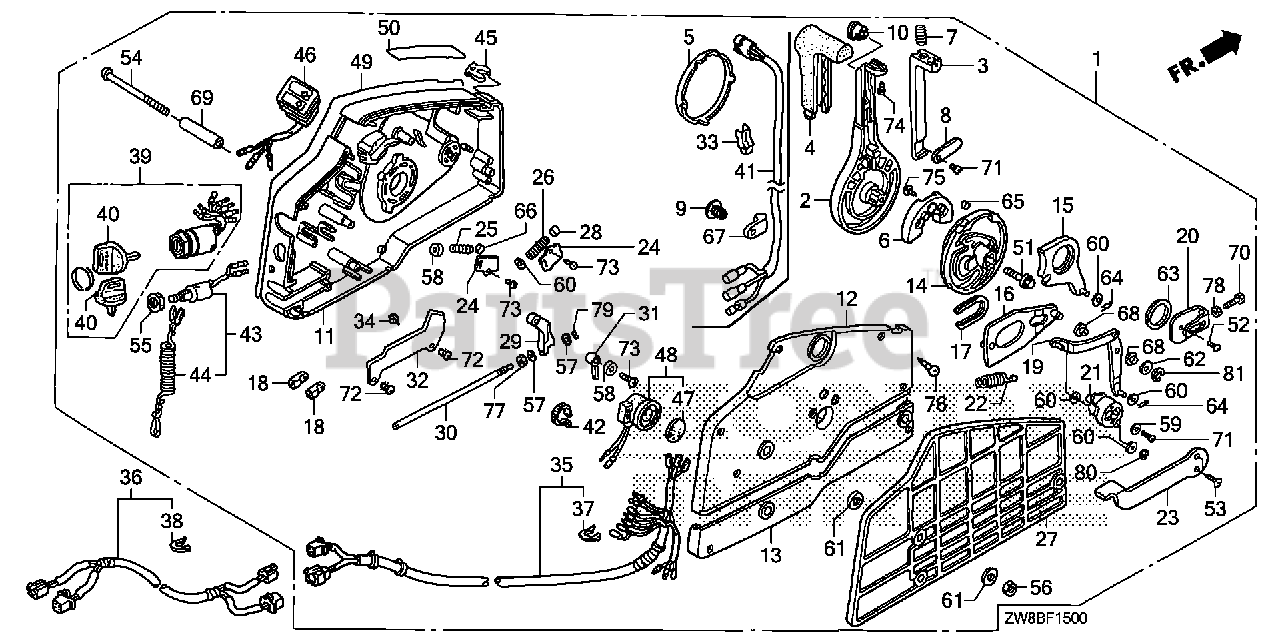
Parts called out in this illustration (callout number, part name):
1	S/R SW 2 LIGH POW TL
1	BOX ASSY., REMOTE CONTROL (PT)
1	BOX ASSY., REMOTE CONTROL (HI-LEX)(PT)
2	HANDLE, REMOTE CONTROL
3	LEVER, HANDLE LOCK
4	GRIP, REMOTE CONTROL HANDLE
5	CAP, HANDLE
6	BLOCK, NEUTRAL LOCK
7	SPRING, REMOTE CONTROL HANDLE
8	PLATE, LEVER SETTING
9	CLAMP, HARNESS
11	HOUSING, REMOTE CONTROL BOX (A)
12	HOUSING, REMOTE CONTROL BOX (B)
13	HOUSING, REMOTE CONTROL BOX (C)
14	WHEEL, CONTROL
15	ARM, SHIFT LINK
16	PLATE, SLIDING
17	COLLAR, SLIDING PLATE
18	PIVOT, SHIFT
19	ARM, LINK JOINT
20	BRACKET, LINK JOINT
21	WHEEL, ACCELERATOR
22	SPRING, ACCELERATOR WHEEL
23	LEVER, IDLE
24	PLATE, SPRING SETTING
25	SPRING, SHIFT CLICK
26	SPRING, CHOKE RETURN
27	SPACER, REMOTE CONTROL BOX
28	SPACER, CLICK SPRING
29	BLOCK, THROTTLE FRICTION
30	BOLT, FRICTION
31	SPACER, NEUTRAL SWITCH
32	CLAMP, POWER TILT CORD
33	PIPE, HARNESS GUIDE
34	SPACER, CABLE CLAMP
35	CABLE ASSY. B, REMOTE CONTROL (4P+6P)
36	CABLE ASSY., REMOTE CONTROL EXTENSION (4P+4P)
36	CABLE ASSY., REMOTE CONTROL EXTENSION (4P+6P)
37	TIE, CABLE (2.4X92) (NATURAL)
38	TIE, CABLE (2.4X92) (NATURAL)
39	SWITCH ASSY., COMBINATION
40	KEY ASSY., COMBINATION SWITCH (35100-ZV5-003 ONLY)
41	SWITCH ASSY., POWER TRIM-TILT
42	BAND (BLACK 3.5X140)
43	SWITCH ASSY., EMERGENCY STOP
44	WIRE, EMERGENCY
45	CLIP, EMERGENCY LOCK
46	LAMP ASSY., INDICATOR
47	PLATE, TURN SIGNAL BUZZER
48	BUZZER, WARNING
49	PLATE, REMOTE CONTROL (CAUTION PICT=SILVER)
49	PLATE, REMOTE CONTROL (COUTION COLOR=RED & YELLOW)
50	MARK, FAST IDLE
51	BOLT, FLANGE (8X35)
52	SCREW, PAN (6X10)
53	SCREW, FLAT (5X12)
54	SCREW (6X95)
55	NUT, HEX. (16MM)
56	NUT, HEX. (6MM)
57	WASHER, PLAIN (4MM)
58	WASHER, PLAIN (5MM)
59	WASHER, PLAIN (5MM)
60	WASHER, PLAIN (6MM)
61	WASHER (6MM)
62	WASHER, PLAIN (8MM)
63	WASHER (28MM)
64	PIN, LOCK (6MM)
65	PIN (6X6)
66	ROLLER, CLICK
67	CLIP, WIRE HARNESS (6.3MM)
68	COLLAR, LINK JOINT
69	COLLAR, DISTANCE (6X10X43.5)
70	BOLT, HEX. (5X16)
71	SCREW, PAN (5X10)
72	SCREW, TAPPING (5X8)
73	SCREW, TAPPING (5X10)
74	SCREW, TAPPING (5X12)
75	SCREW, TAPPING (6X16)
76	SCREW, TAPPING (5X25)
77	NUT, HEX. (6MM)
78	NUT, HEX. (5MM)
79	E-RING (3MM)
80	E-RING (4MM)
81	E-RING (7MM)
